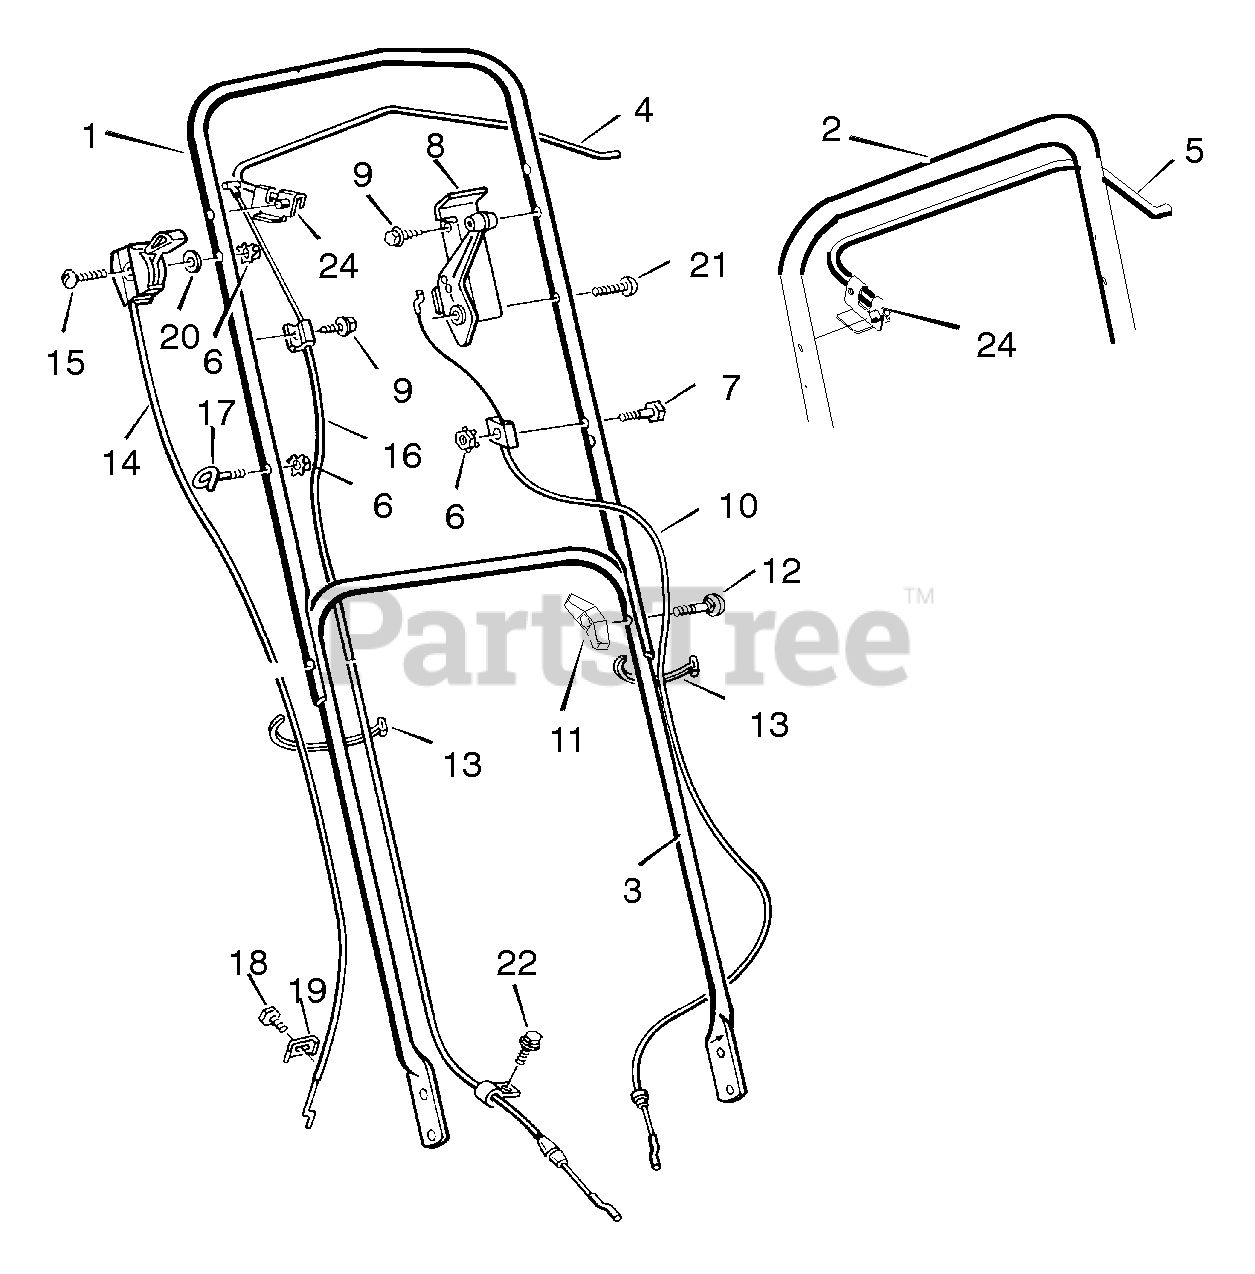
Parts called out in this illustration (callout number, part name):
1	Handle, Upper- Curved (Black)
2	Handle, Upper-Straight (Black)
3	Handle, Lower (Black)
4	Lever, Stop - Curved
5	Lever, Stop- Straight
6	Locknut
8	Drive Control
10	Cable, Drive
11	Knob
13	Fastener, Cable
14	Throttle Control
16	Engine Stop Cable *
17	GUIDE, ROPE
18	Screw *
19	Clamp
20	Washer
24	Bracket, Stop Lever
